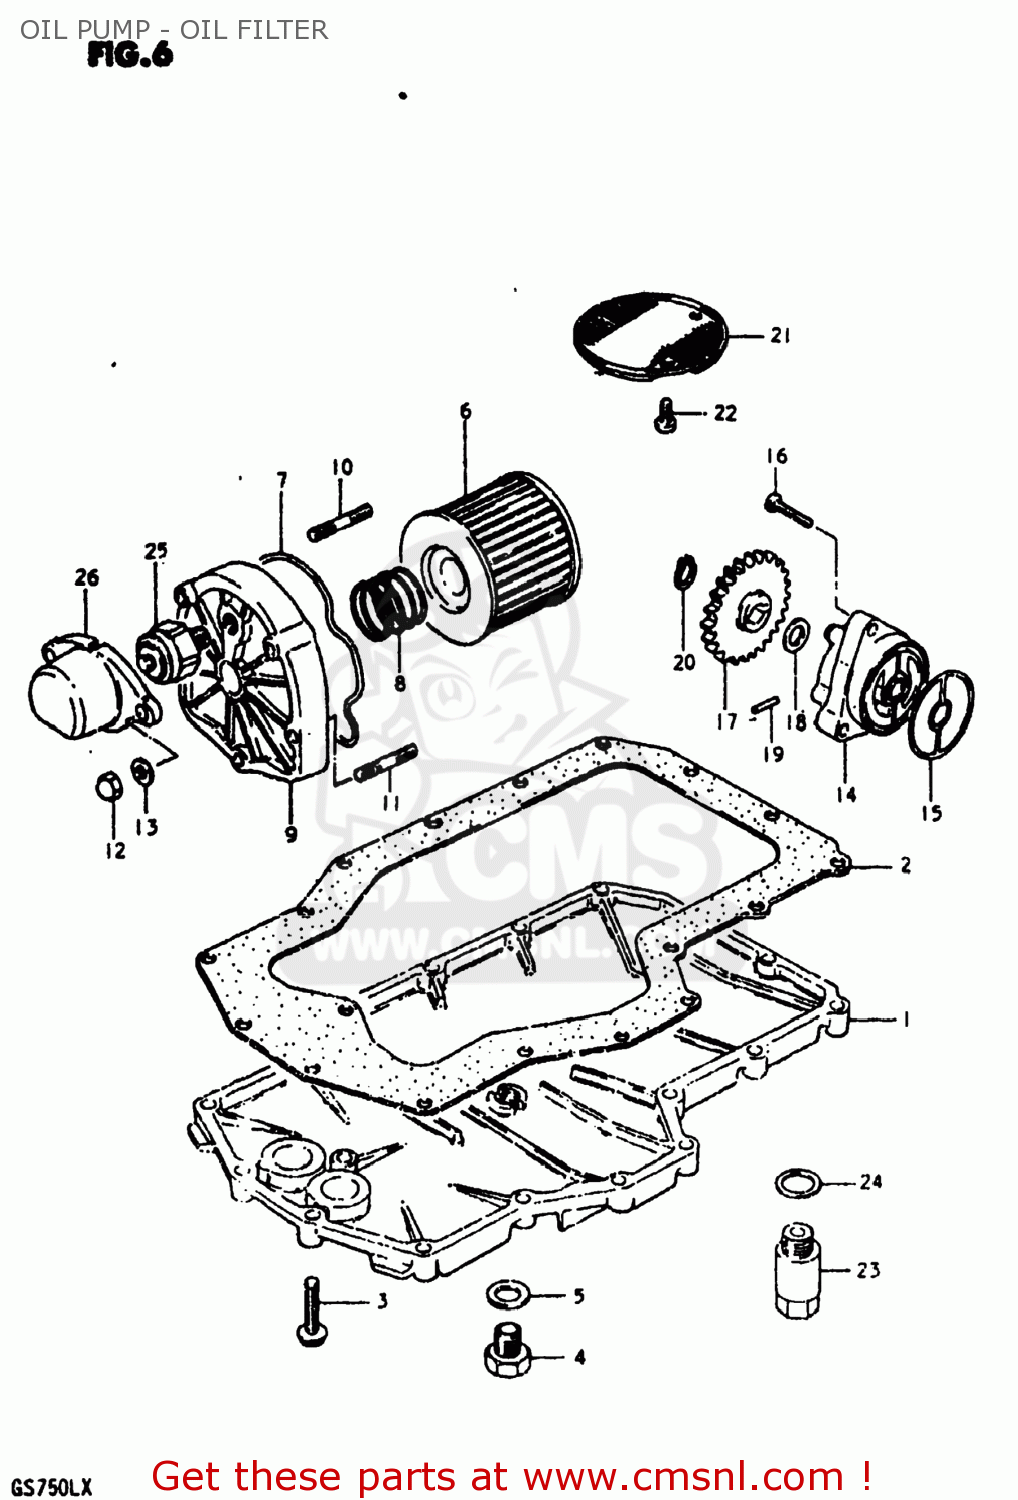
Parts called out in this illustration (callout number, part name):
1	PAN,OIL
2	GASKET,OIL PAN (MCA)
3	BOLT
4	PLUG
5	GASKET(14X19.2X2) (NAS)
6	FILTER ASSY,ENGINE OIL
7	O RING,OIL FILTER CHAMBER CAP
8	SPRING
9	CAP,ENGINE OIL FILTER
10	STUD 6X30
11	STUD 6X25
12	NUT
13	WASHER
14	PUMP ASSEMBLY,OIL
15	O-RING,OIL PUMP
16	SCREW
17	GEAR,ENG OIL PUMP DRIVEN
18	SHIM
19	PIN(4X15.8)
20	CIRCLIP
21	STRAINER,ENGINE OIL
22	SCREW 6X12
23	VALVE ASSEMBLY,OIL RELIEF
24	WASHER
25	SWITCH ASSEMBLY
26	COVER,OIL PRESSURE SWITCH
